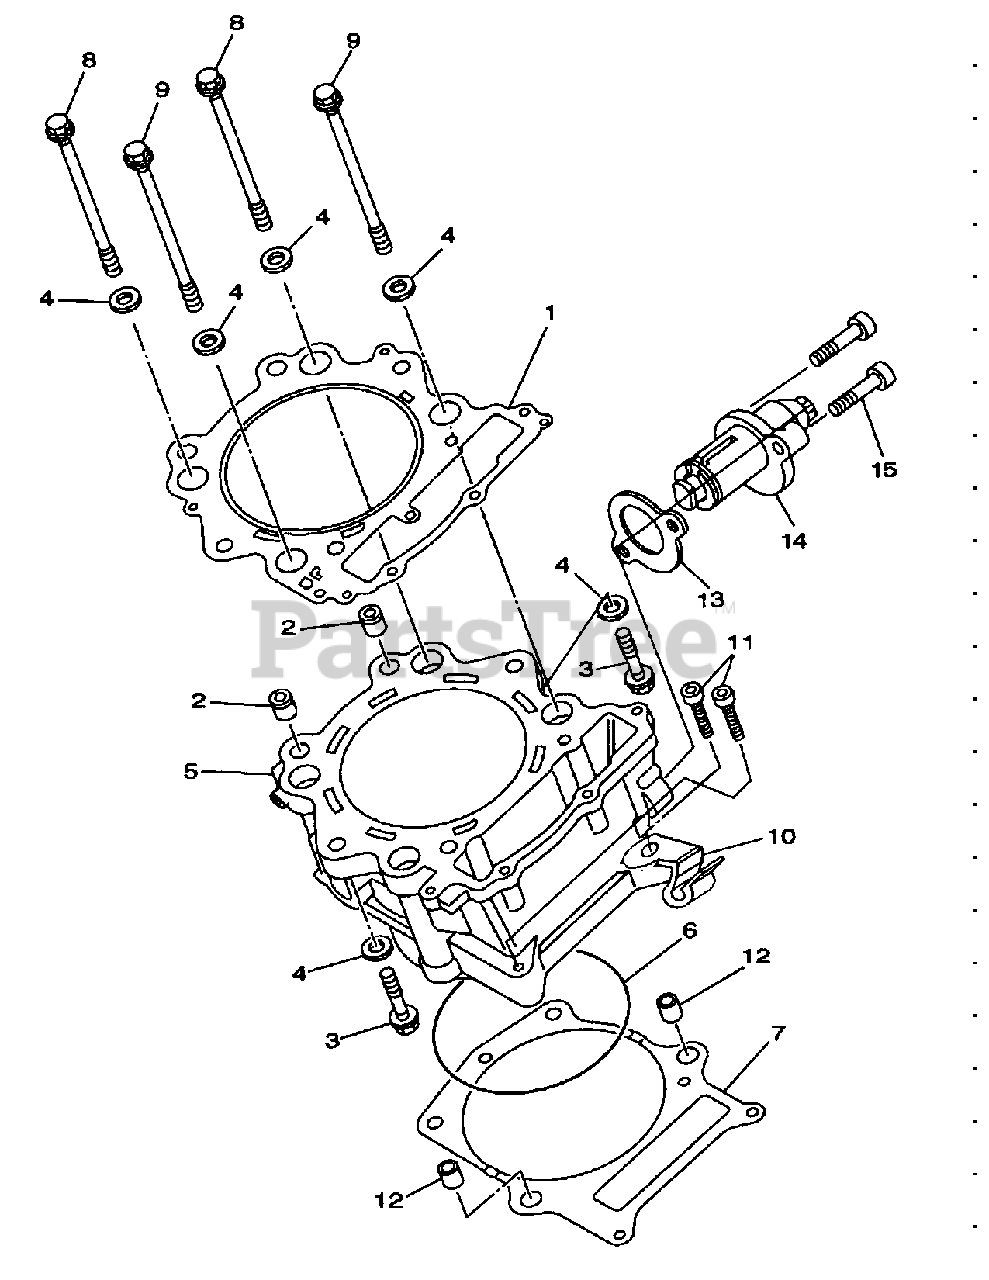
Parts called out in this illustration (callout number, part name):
1	Gasket-Cylinder Head
3	Flangebolt M9X38.5
4	Washer
5	Cylinder Body-Complete
6	O-Ring 105.7X2.8
7	Gasket-Cylinder Body
8	Bolt M10X108.5
11	Screw-Cylinder M6
13	Tensioner Gasket
14	Tensioner-Complete
15	Screw-Cylinder M6
